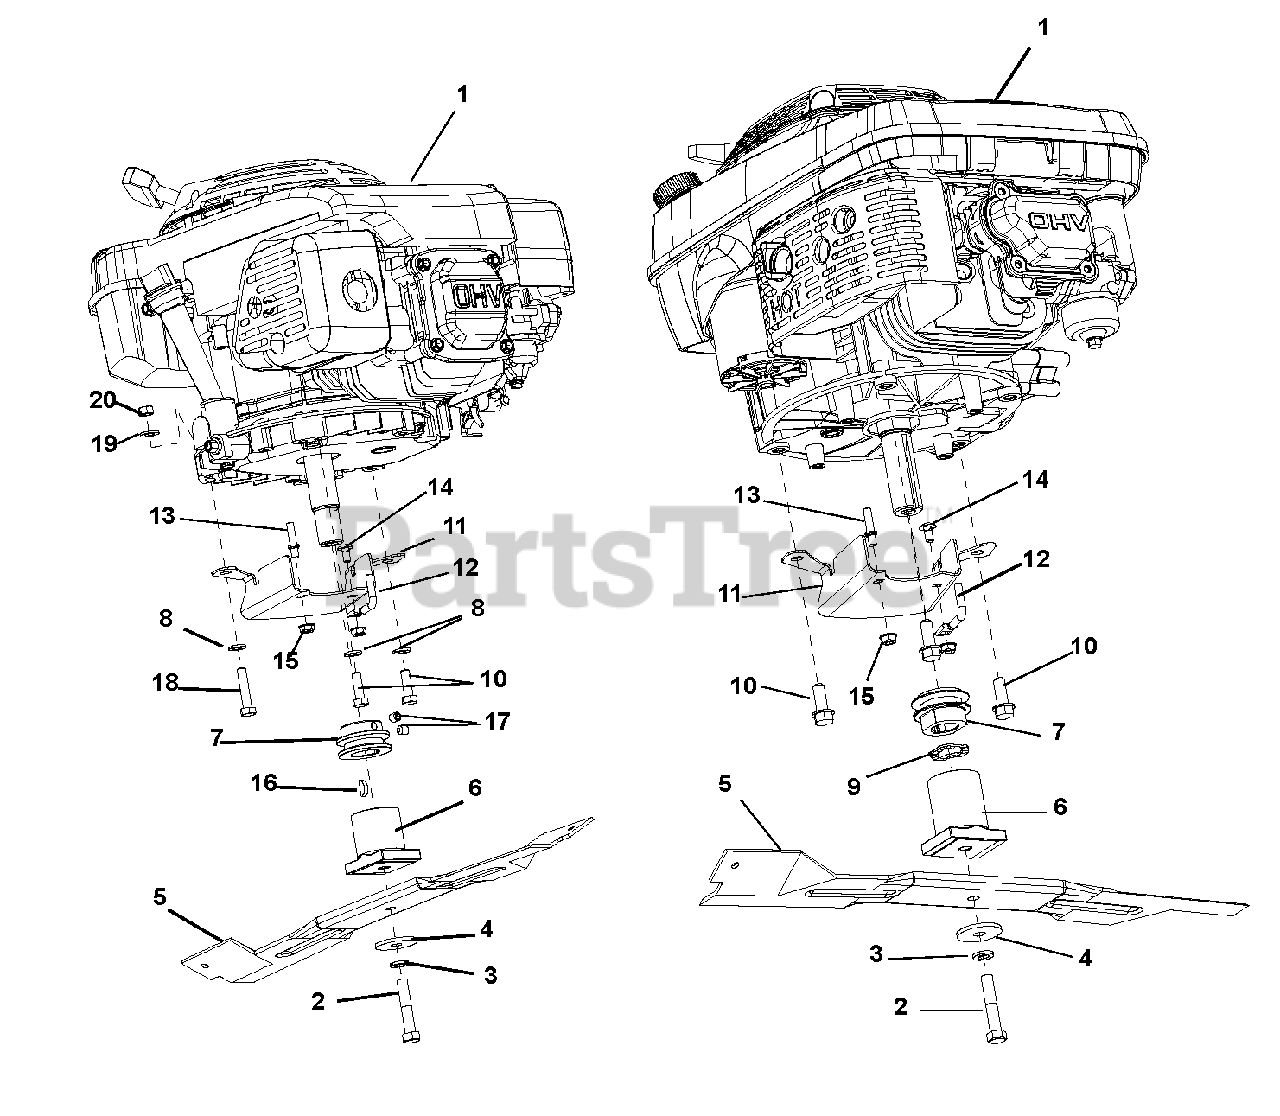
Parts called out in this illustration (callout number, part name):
1	Engine, 6.0 HP KAWI U.S. COMMERICIAL (911253)
2	Bolt, Hex .38-24 x 2.00 Grade 8
3	Washer, Locking .38 x .094 Regular
4	Washer, Flat-Steel .39 x 1.5 x .125
5	21" Mower Blade
6	Adapter, CE Blade (911253)
7	Pulley-Sintered Iron LM (911253)
8	Washer, Locking .31 x .078 Regular (911251, 255)
9	Washer, Wave .885 x 1.311 x .125 (911253)
10	Screw, Tapping .38-16 x 1.00 Hex Washer Head Thread (911253)
11	Channel, XD21 Front Belt
12	Finger, Belt
13	Finger, Belt
14	Bolt, Round Head Square Neck .25-20 x .50 Grade 5
15	Nut, Locking-Flange .250-20
16	Key, Woodruff .156 x .625 x .25 (911251, 255)
17	Screw, Set .31-18 x .38 Socket Head (911251, 255)
18	Bolt, Hex .31-24 x 1.50 Grade 5 (911251, 255)
19	Washer, Flat-Steel .344 x .688 x .065 (911251, 255)
20	Nut, Hex .312-24 (911251, 255)
